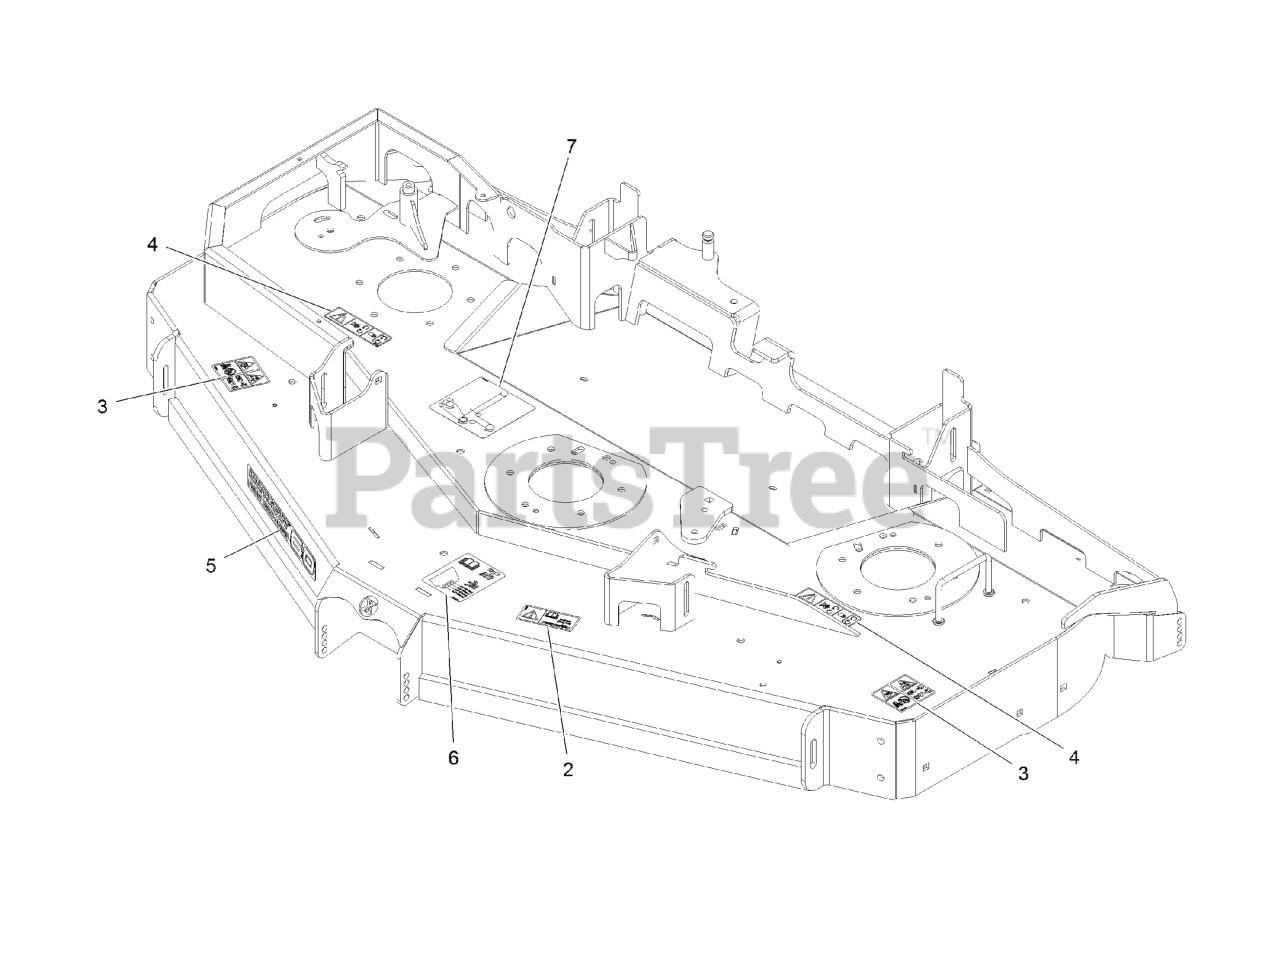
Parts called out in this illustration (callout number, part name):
2	DECAL-TORQUE, BOLT
3	DECAL-DANGER, THROWN OBJECT
4	DECAL-COVER, MISSING
5	DECAL, 60RD
6	DECAL-ROLLER, ANTI-SCALP
7	DECAL-ROUTING, BELT
